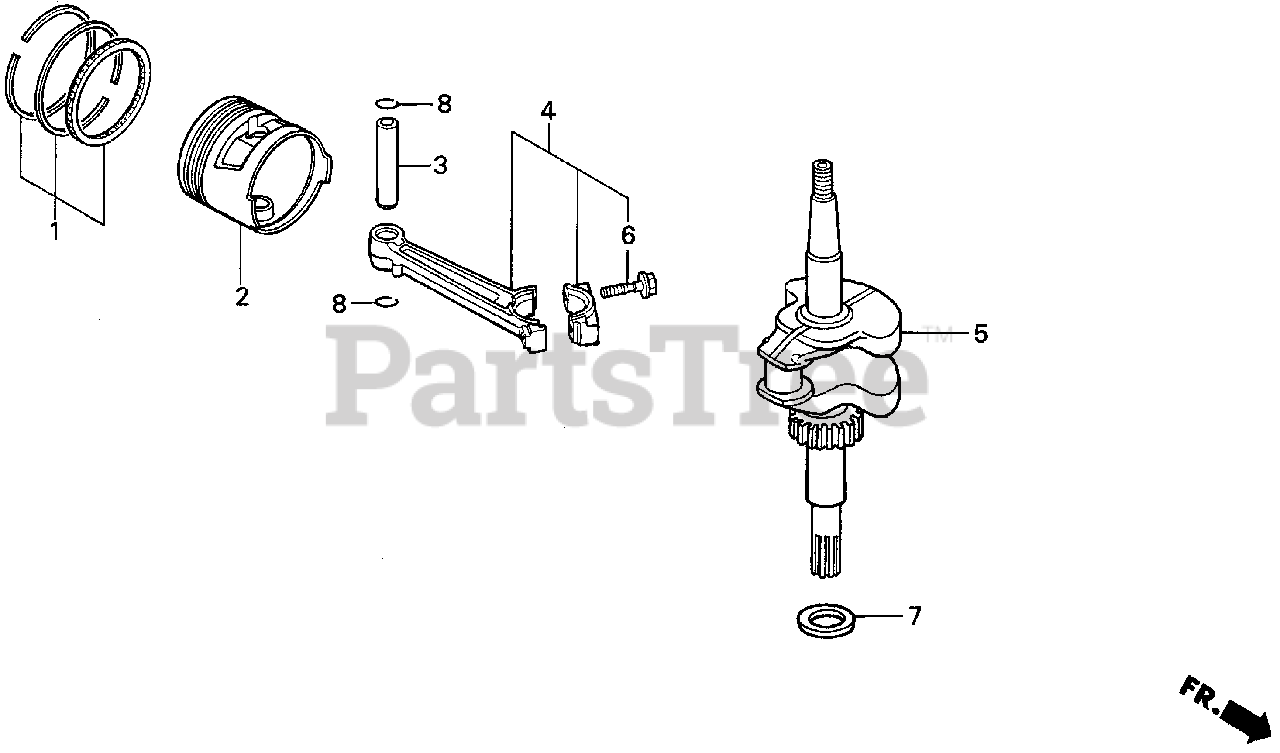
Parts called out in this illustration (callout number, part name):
1	RING SET, PISTON (STD)
3	PIN, PISTON
4	ROD ASSY., CONNECTING
5	CRANKSHAFT
6	BOLT, CONNECTING ROD
7	WASHER C, THRUST (25MM)
8	CLIP, PISTON PIN (18MM)
